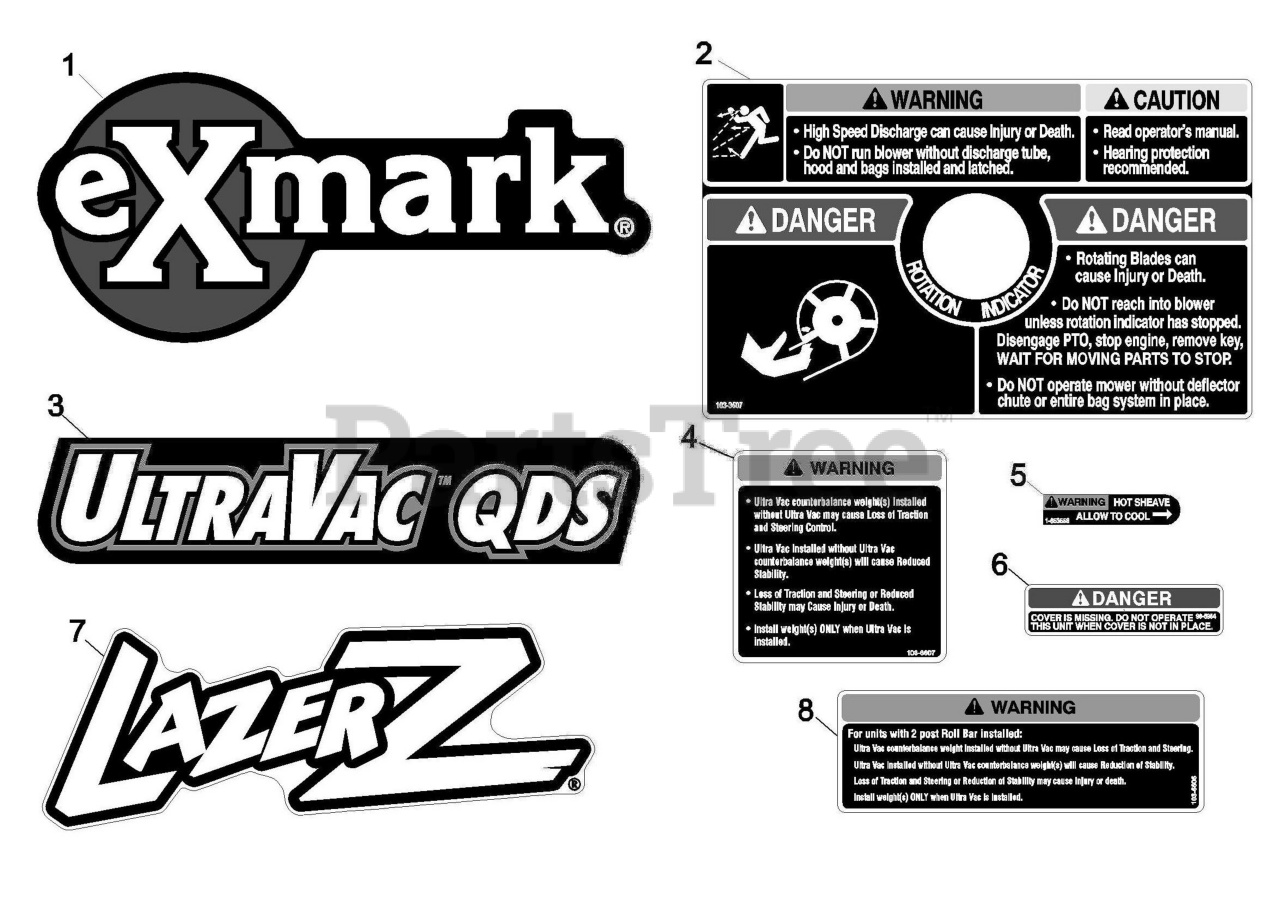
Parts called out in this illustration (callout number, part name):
1	DECAL, EXMARK
3	DECAL, ULTRAVAC QDS
4	DECAL,WEIGHT
5	DECAL-WARNING
6	DECAL-COVER, MISSING
7	DECAL,LAZER MODEL
8	DECAL,WEIGHT
